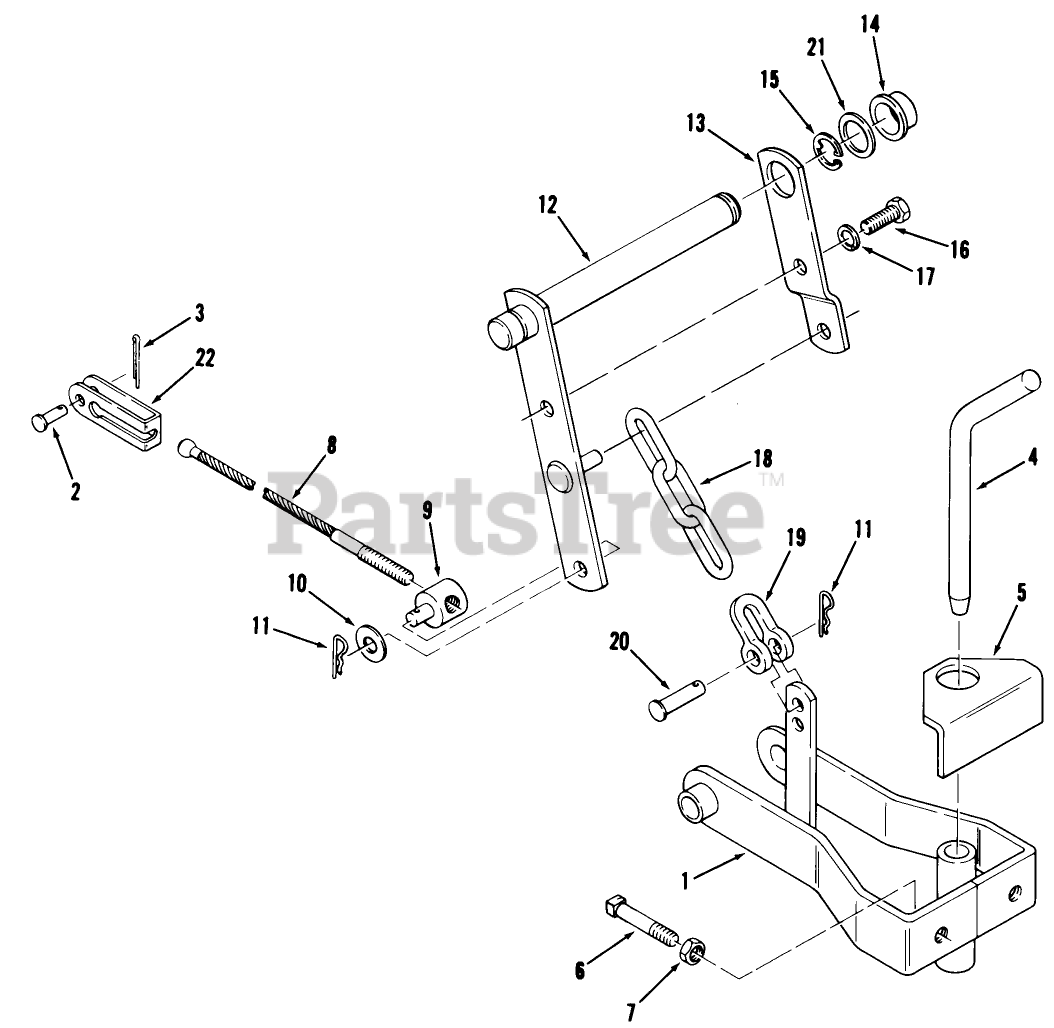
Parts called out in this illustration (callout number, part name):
1	ASSY-HITCH R (NS)
2	Pin
3	Cotter Pin
4	PIN-HITCH
5	PLATE ADJ HITCH R
6	SCREW
7	Jam Nut
8	CABLE
9	TRUNNION-CLUTCH ROD
10	Washer
11	Hairpin
12	ASSY-LEVER R
13	LOCK BRACKET R
14	BUSHING-BRONZE
15	E-RING
16	Bolt
17	Lockwasher
18	CHAIN-LIFT
19	Clevis
20	Clevis Pin
21	WASHER-SHIM
21	WASHER
22	CLEVIS-SHORT
22	CLEVIS-LONG
